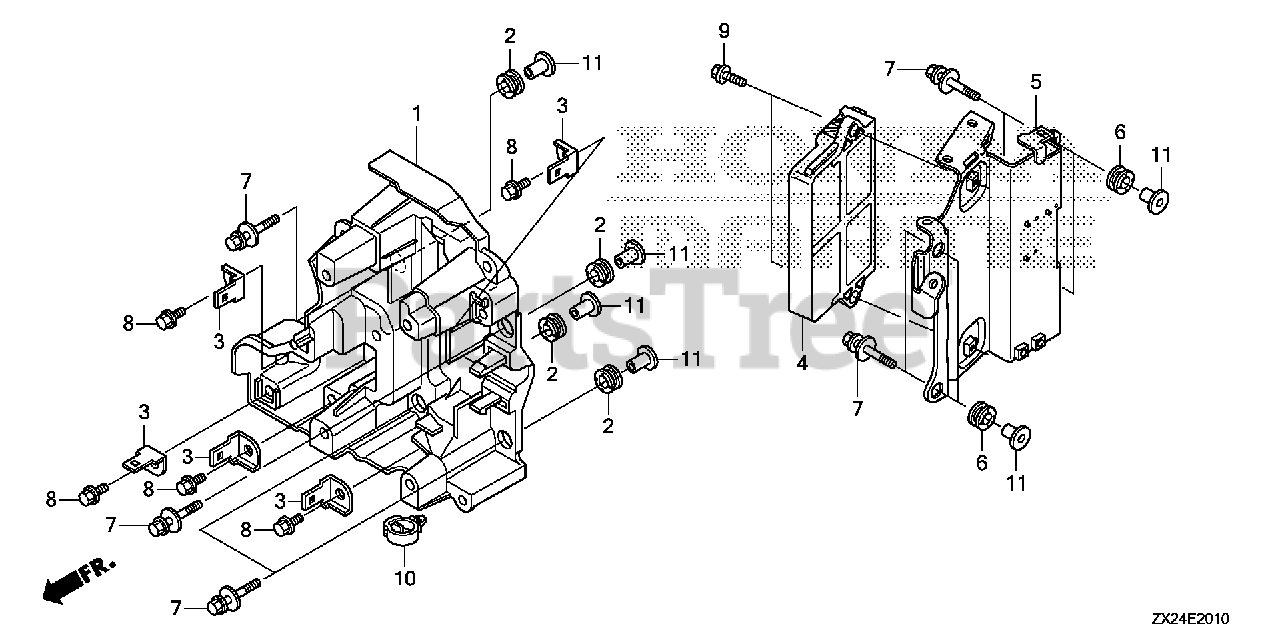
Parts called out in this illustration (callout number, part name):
1	CASE, ELECTRONIC PARTS
2	GROMMET, ELECTRONIC PARTS CASE
3	BRACKET, ALTERNATOR FUSE
4	CONTROL UNIT, ELECTRONIC
5	BRACKET, ECU
6	GROMMET, RELAY BRACKET
7	BOLT-WASHER (6X27) (CT200)
7	BOLT-WASHER (6X27)
8	BOLT, FLANGE (6X10)
9	BOLT, FLANGE (6X20)
10	CLIP, WIRE HARNESS (25MM)
11	COLLAR, MODULE IGNITION CONTROL CASE (CDI)
